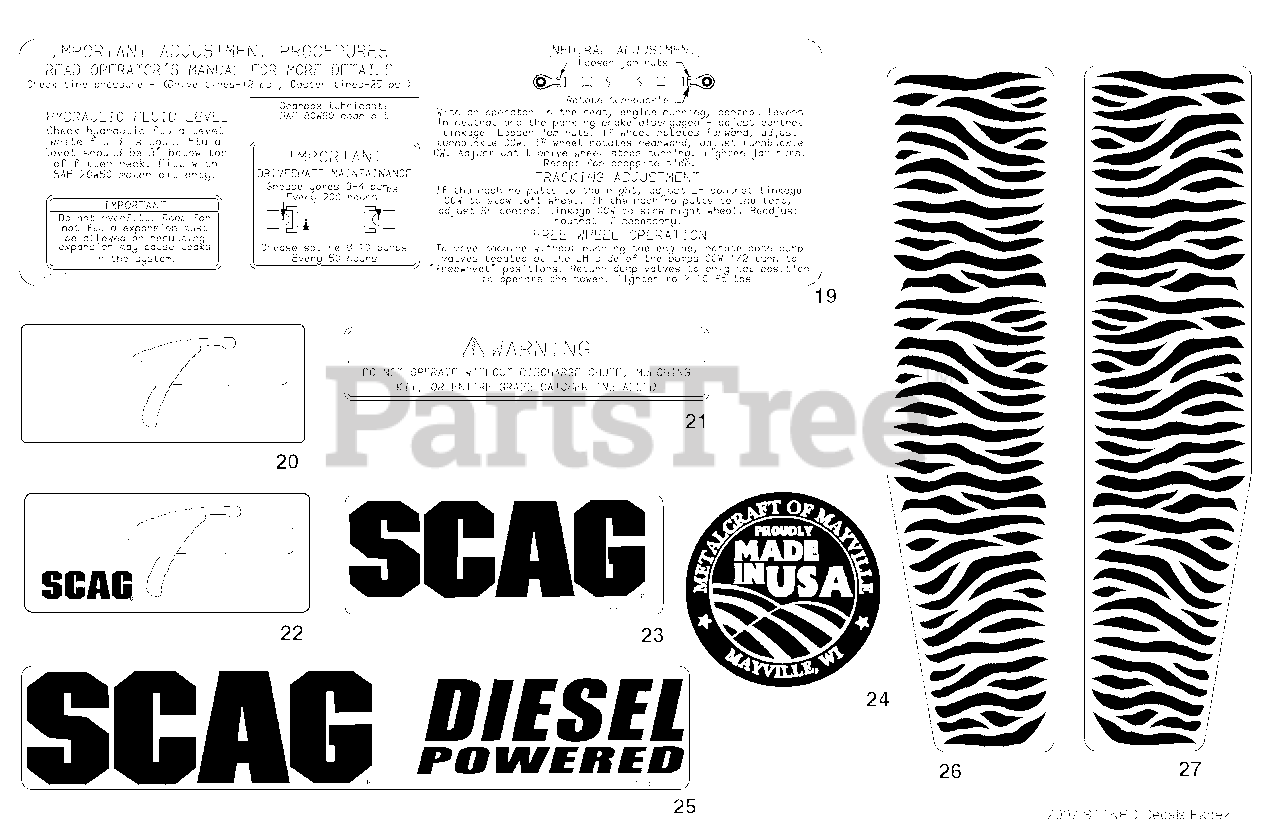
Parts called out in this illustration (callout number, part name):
19	Decal, Checks and Adjustments
20	Decal, Turf Tiger
21	Decal, Warning
22	Decal, Turf Tiger
23	Decal, Scag Logo
24	Decal, Metalcraft-Made In USA
25	Decal, Scag Diesel Powered
26	Decal, Stripes-RH
27	Decal, Stripes-LH
